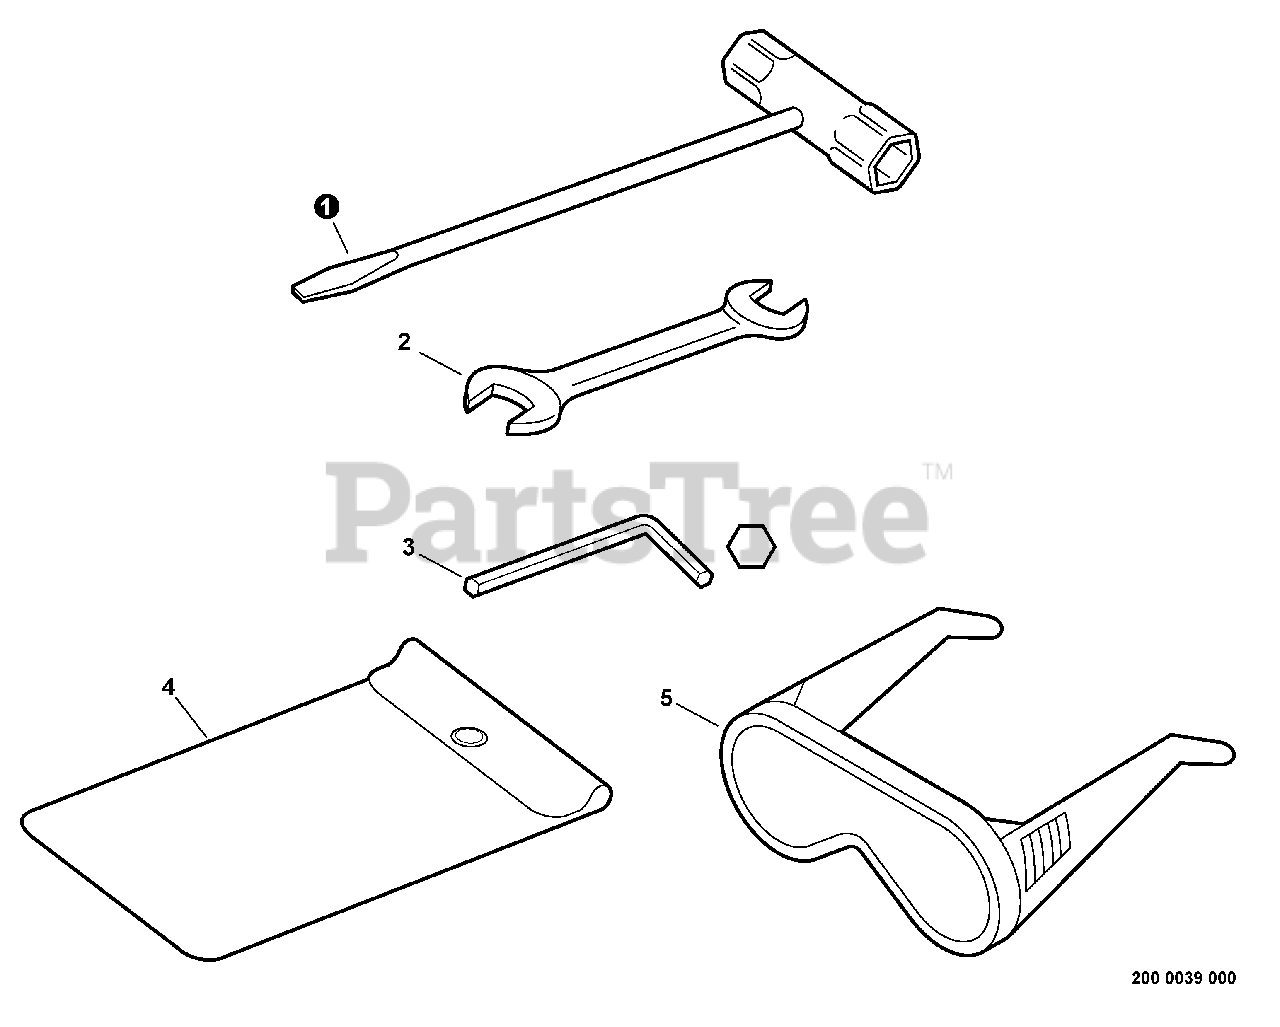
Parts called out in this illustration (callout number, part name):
1	T-WRENCH - 17X19mm
2	SPANNER - 8X10mm
3	HEX KEY - 4mm
4	BAG, TOOL
5	GOGGLES
